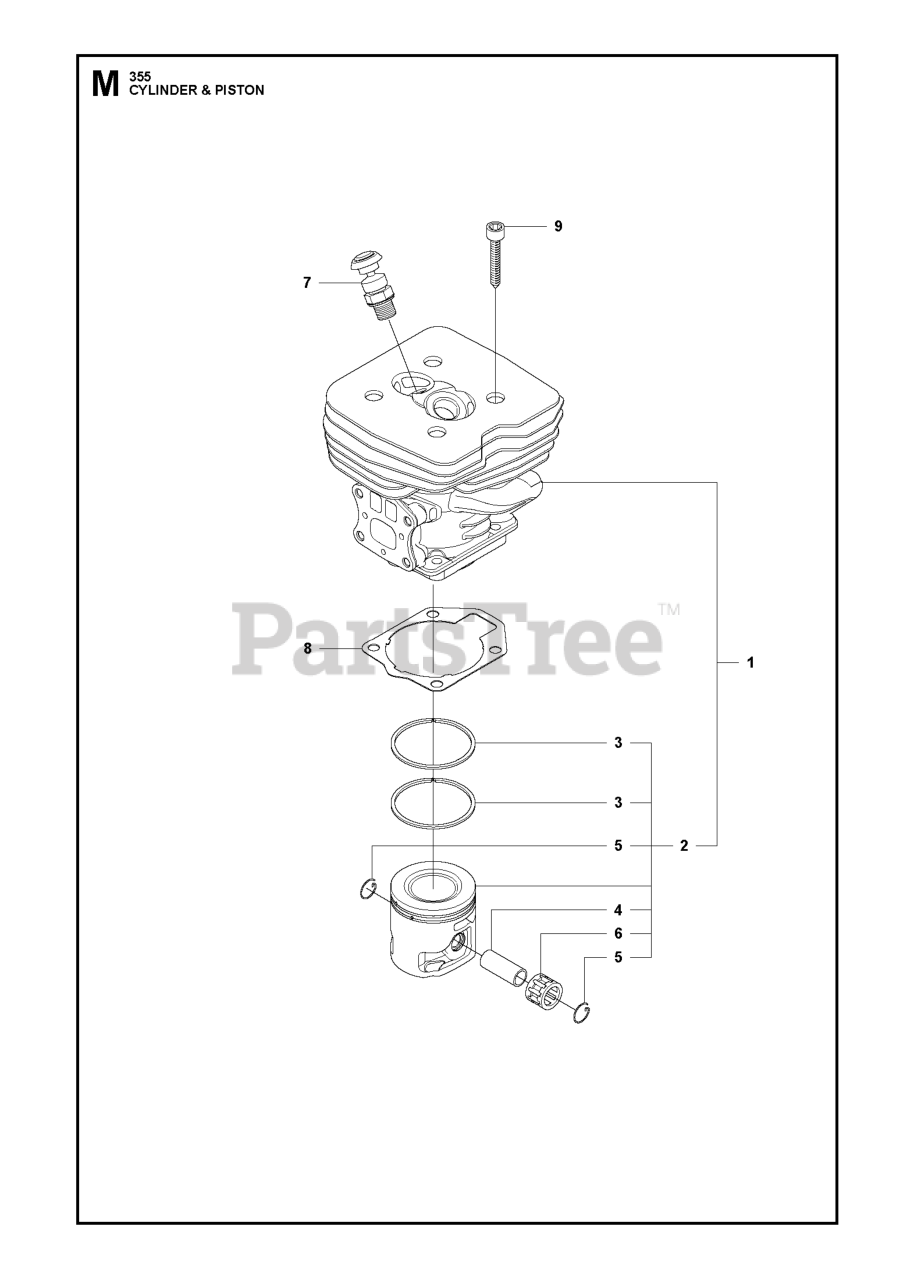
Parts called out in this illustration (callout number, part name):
1	CYLINDER ASSY
2	PISTON ASSY
3	PISTON RING
4	PISTON PIN
5	CIRCLIP B10X0.8
6	NEEDLE BEARING
7	DECOMPRESSION VALVE
9	SCREW MC6S 5X25
